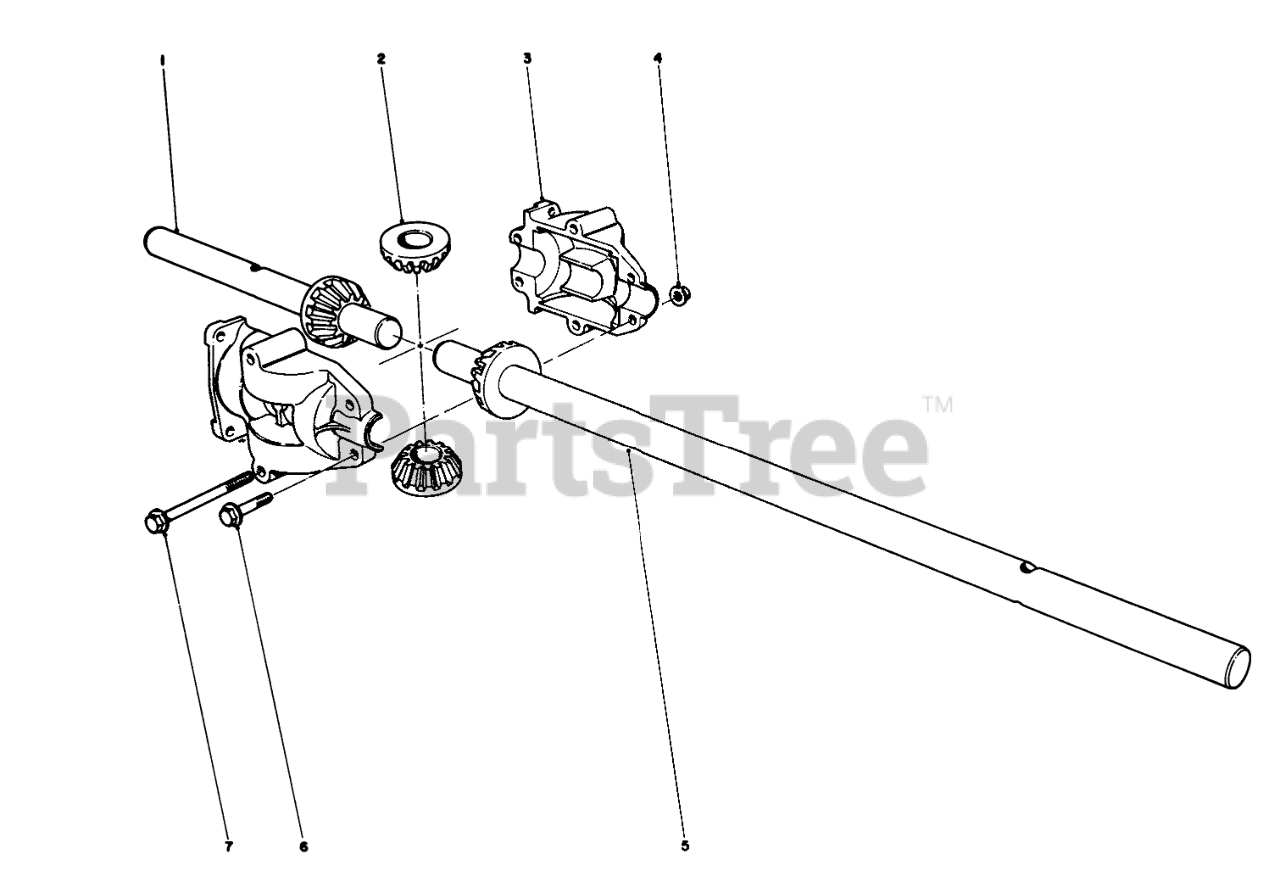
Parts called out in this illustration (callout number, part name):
1	SHORT SHAFT
2	MITER GEAR
3	DIFF HSG
4	NUT-HHF
5	LONG SHAFT
